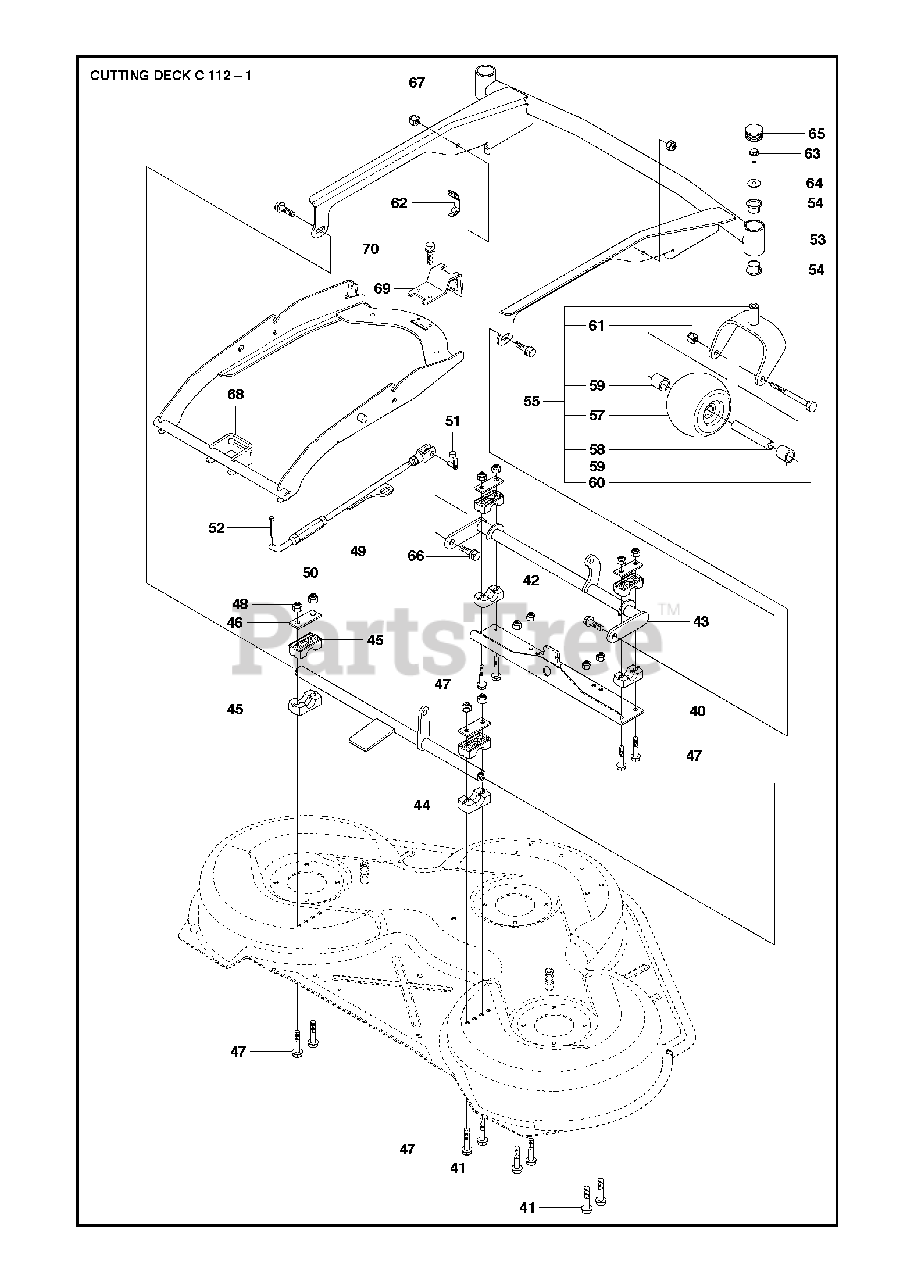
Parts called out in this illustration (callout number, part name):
42	LOCKNUT M8
48	LOCKNUT M8
49	PARALLELL ROD ASSY
50	PARALLEL ROD
51	RETAINER
53	DECK FRAME
55	PIVOT WHEEL ASSY
57	DECK ROLLER, FRONT
58	PIPE
59	SPACER
60	BOLT
61	NUT
62	CLIP GRAY
67	LOCKNUT M8
68	DECK ATTACHMENT
70	Screw
